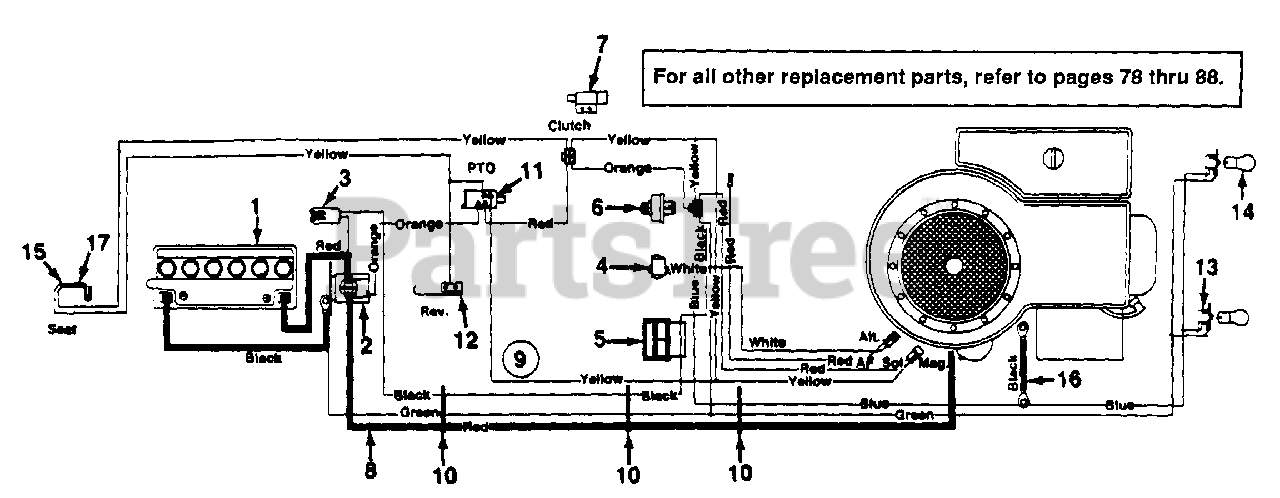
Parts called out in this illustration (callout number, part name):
1	Battery
2	Solenoid
3	Fuse 7.5 Amps
4	Light Switch
5	Ammeter
6	Ignition Switch
7	Safety Switch (Clutch)
8	Electric Wire 30" Lg.
9	Wire Harness w/Ammeter
10	Cable Tie
11	Safety Switch (Deck)
12	Safety Switch (Reverse)
13	Socket
14	Bulb (Headlight)
15	Safety Switch (Seat)
16	Ground Wire 7.5" Lg.
17	Safety Switch (Seat)
